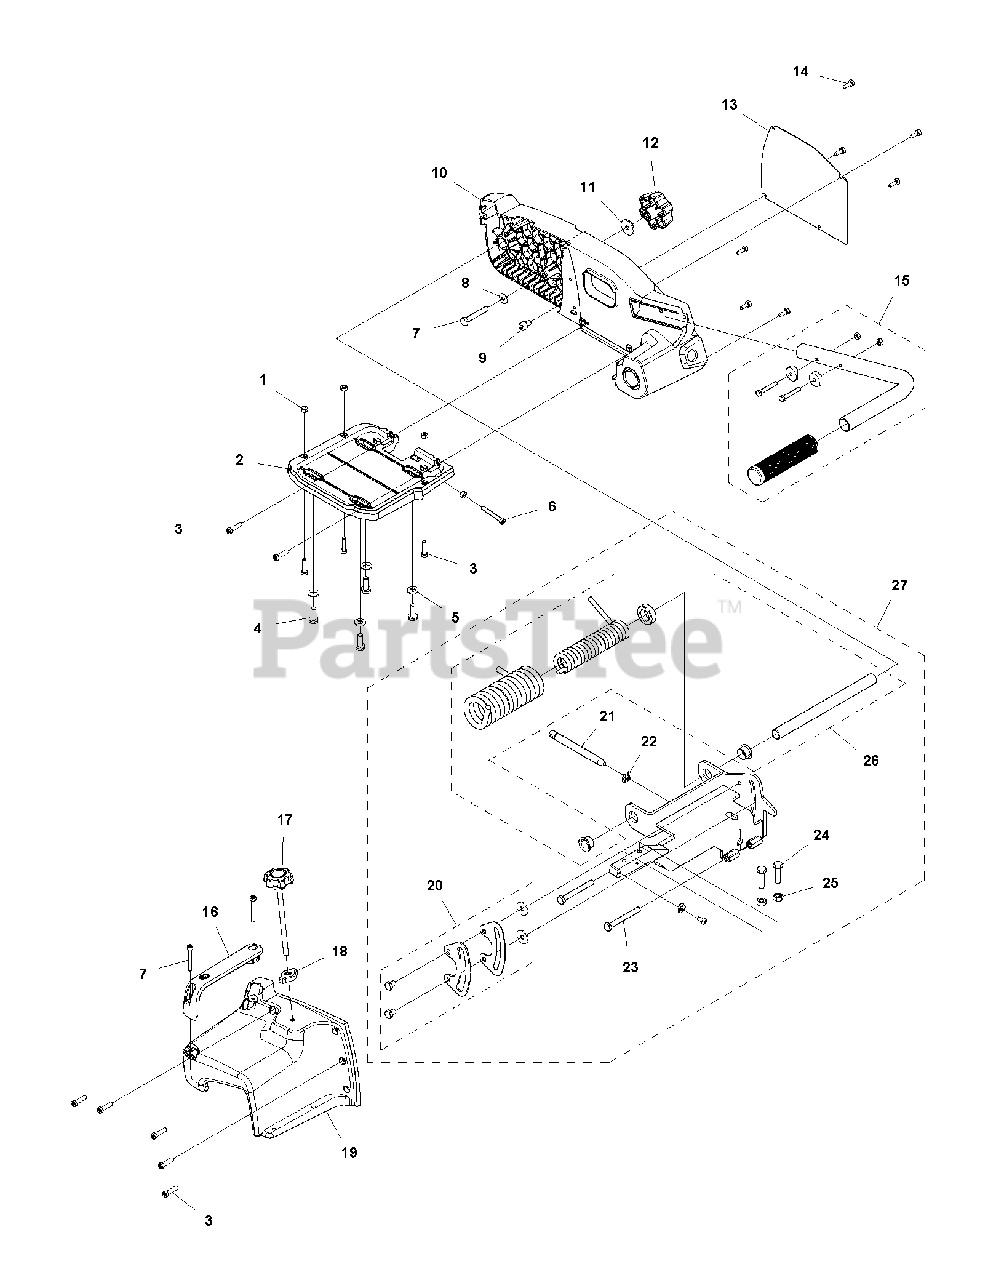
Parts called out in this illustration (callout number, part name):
1	HEXAGON LOCKING NUT
3	SCREW IHSCM
5	WASHER
25	HEXAGON NUT
